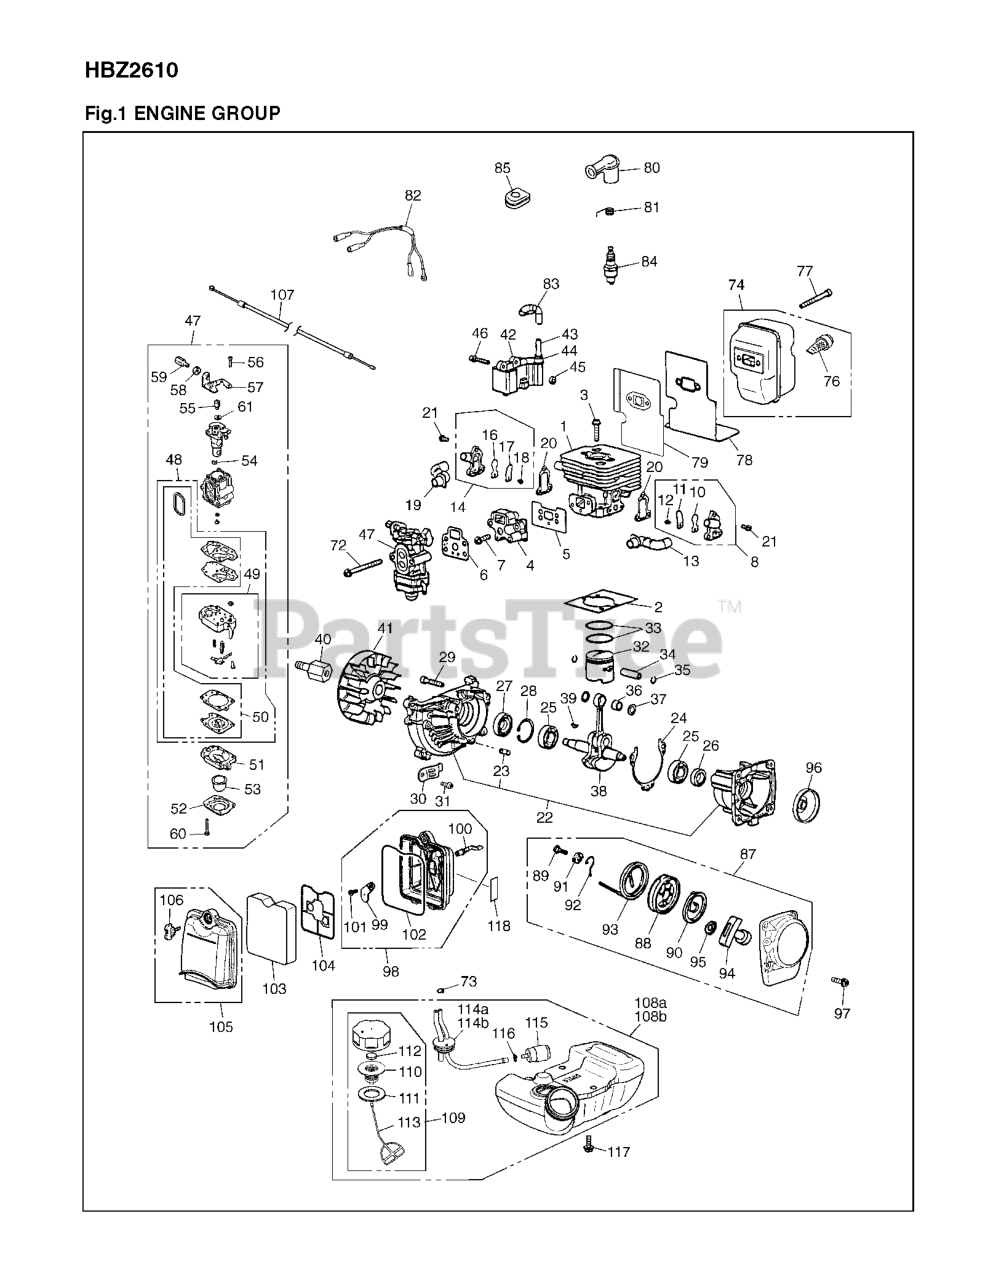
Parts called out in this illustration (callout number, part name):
1	CYLINDER
2	GASKET, BASE
3	BOLT
4	INSULATOR
5	GASKET.INSU
8	REEDVALVE(S)-A
13	PIPE AIR (S)
14	REEDVALVE(F)-A
19	PIPE AIR (F)
20	GASKET, VALVE
21	BOLT
22	CRANKCASE-C
23	PIN
24	GASKET.CASE
27	SEAL
34	PIN (RPLS T151341310)
36	BEARING (R550041410&114041330)
38	CRANKSHAFT COMP(RPLS481042000)
39	KEY
40	EXTENSION.
43	CORD (BLACK)
44	CAP
45	SPACER
47	CARBURETOR-A
48	REBUILD KIT
49	CARBURETOR BODY
50	GASKET KIT
52	1OVER
54	RING
55	SWIVEL
56	SCREW
57	BRACKET
58	NUT
59	ADJUSTER
61	WASHER
73	CLIP
74	MUFFLER-A
76	ARRESTER
78	GASKET, MUFFLER
79	PLATE, MUFFLER
84	PLUG CMR7H
85	GROMMET
87	RECOIL-A
90	SPRING, SPIRAL
91	COLLAR
92	SWING ARM
95	PLATE.STOPPER
98	BODY A
99	PLATE.CHOKE
100	LEVER CHOKE
101	SCREW
103	ELEMENT
105	COVER A (RPLS T151382200)
110	HOLDER-A
115	FILTER
116	CLIP
118	LABEL, CHOKE
